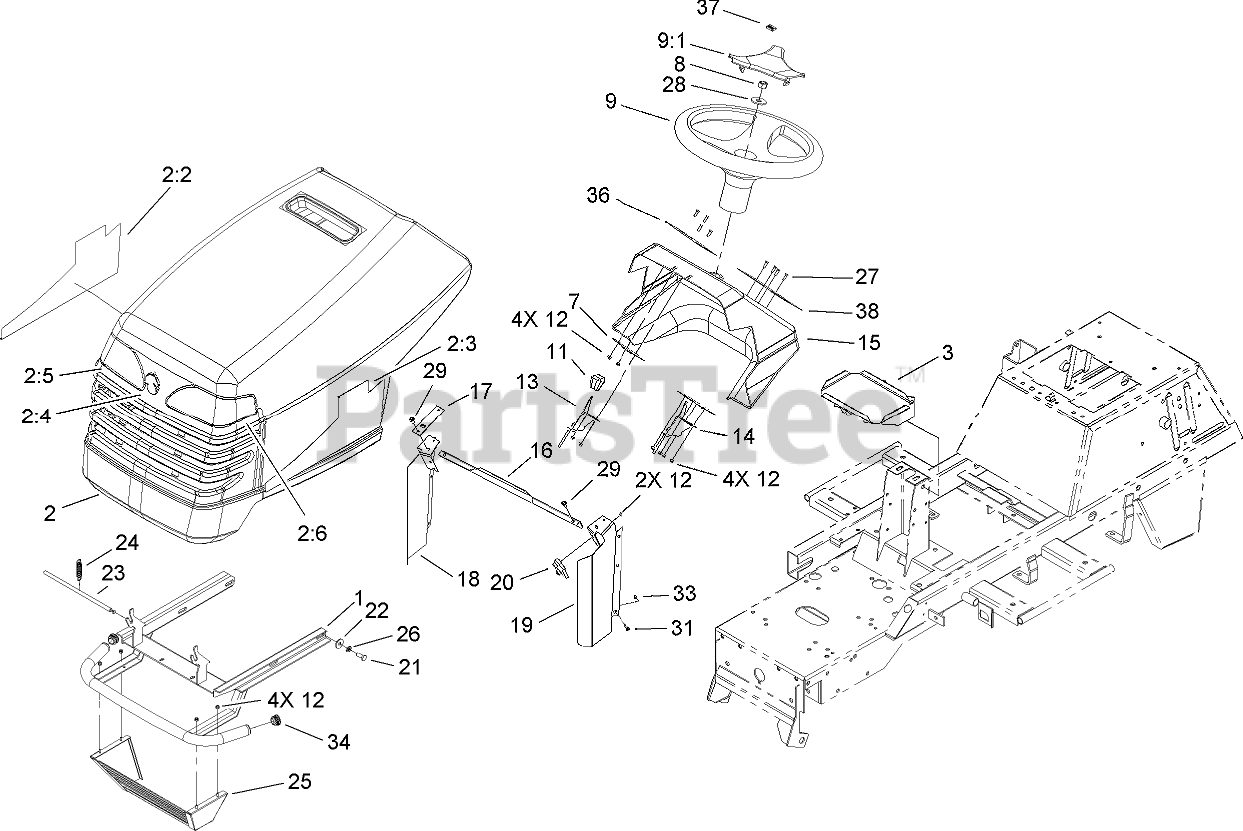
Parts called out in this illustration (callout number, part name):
1	SUPPORT-BUMPER
2	HOOD ASM
2:2	DECAL-HOOD, RH
2:3	DECAL-HOOD, LH
2:4	EMBLEM
2:5	LENS-HEADLAMP, RH
2:6	LENS-HEADLAMP, LH
3	TRAY-BATTERY
8	NUT-LOCK
9	WHEEL-STEERING
9:1	COVER-WHEEL, STEERING
12	NUT-LOCK
13	CONTROL-THROTTLE (TWIN)
14	CONTROL-CHOKE (TWIN)
15	PANEL-DASH
17	BRACKET
18	PANEL-RIGHT
19	PANEL-LEFT
20	LATCH-HOOD
21	SCREW-HH
22	WASHER-PLAIN
23	BAR-SAFETY
24	SPRING-HOOD
25	GUARD-MUFFLER
26	WASHER-LOCK, SPRING
28	Washer
33	NUT-HEX
34	PLUG-END, TUBE
36	DECAL
37	DECAL
38	DECAL-CHOKE/PTO
